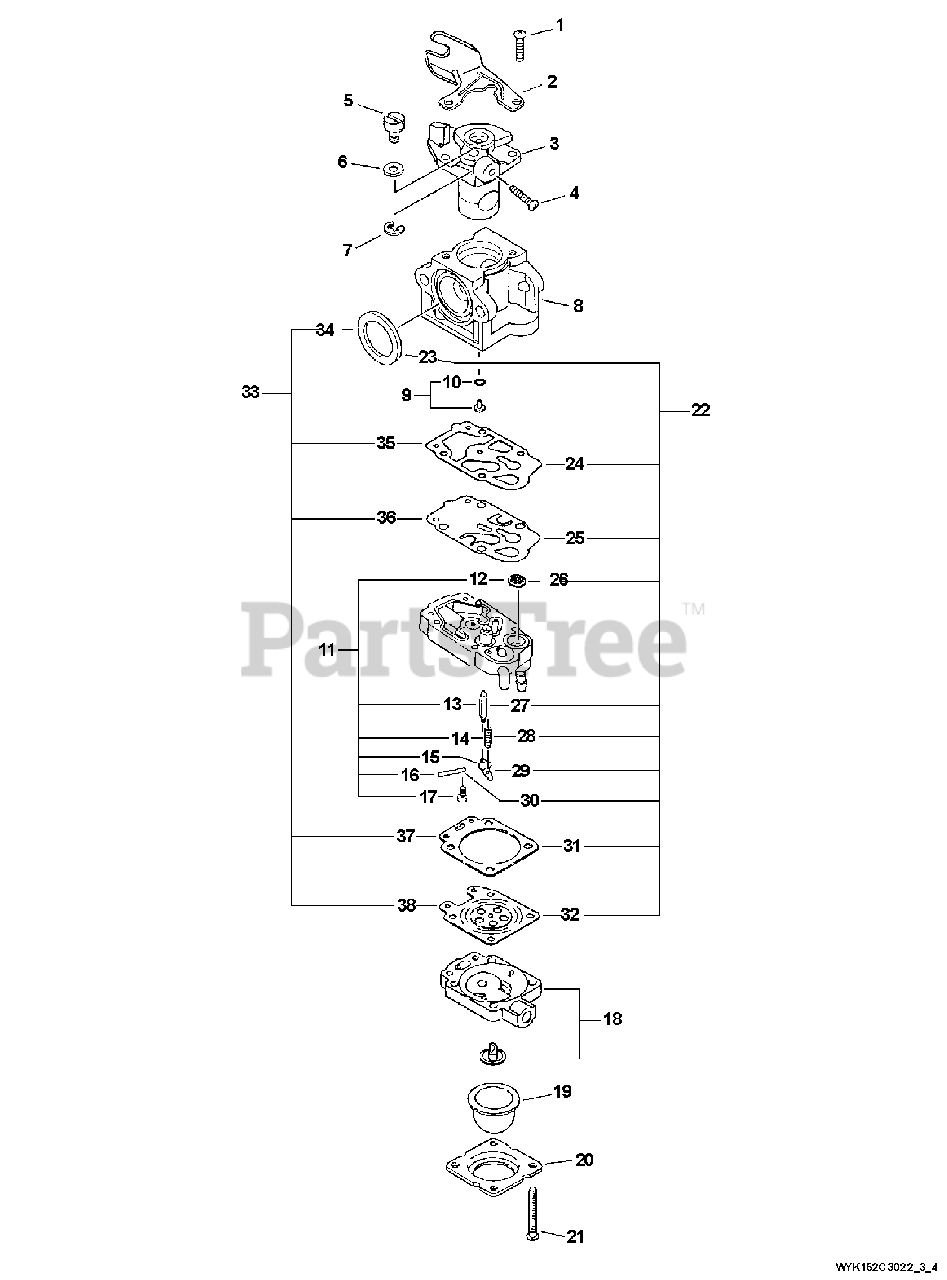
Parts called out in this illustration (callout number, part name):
2	BRACKET, CABLE
3	THROTTLE VALVE ASSY
4	SCREW, IDLE ADJUST
7	RING, RETAINING
8	BODY, CARBURETOR
9	JET KIT
11	PUMP BODY ASSY
12	STRAINER
13	VALVE, INLET NEEDLE
14	SPRING, METERING LEVER
15	LEVER, METERING
16	PIN, METERING LEVER
17	SCREW, METERING LEVER PIN
18	PURGE BASE ASSY
19	BULB, PURGE
20	RETAINER, PURGE BULB
21	SCREW, PUMP COVER
22	REPAIR KIT
23	SEAL
24	GASKET, PUMP
25	DIAPHRAGM, PUMP
26	STRAINER
27	VALVE, INLET NEEDLE
28	SPRING, METERING LEVER
29	LEVER, METERING
30	PIN, METERING LEVER
31	GASKET, DIAPHRAGM
32	DIAPHRAGM, METERING
33	DIAPHRAGM/GASKET KIT
34	SEAL
35	GASKET, PUMP
36	DIAPHRAGM, PUMP
37	GASKET, DIAPHRAGM
38	DIAPHRAGM, METERING
